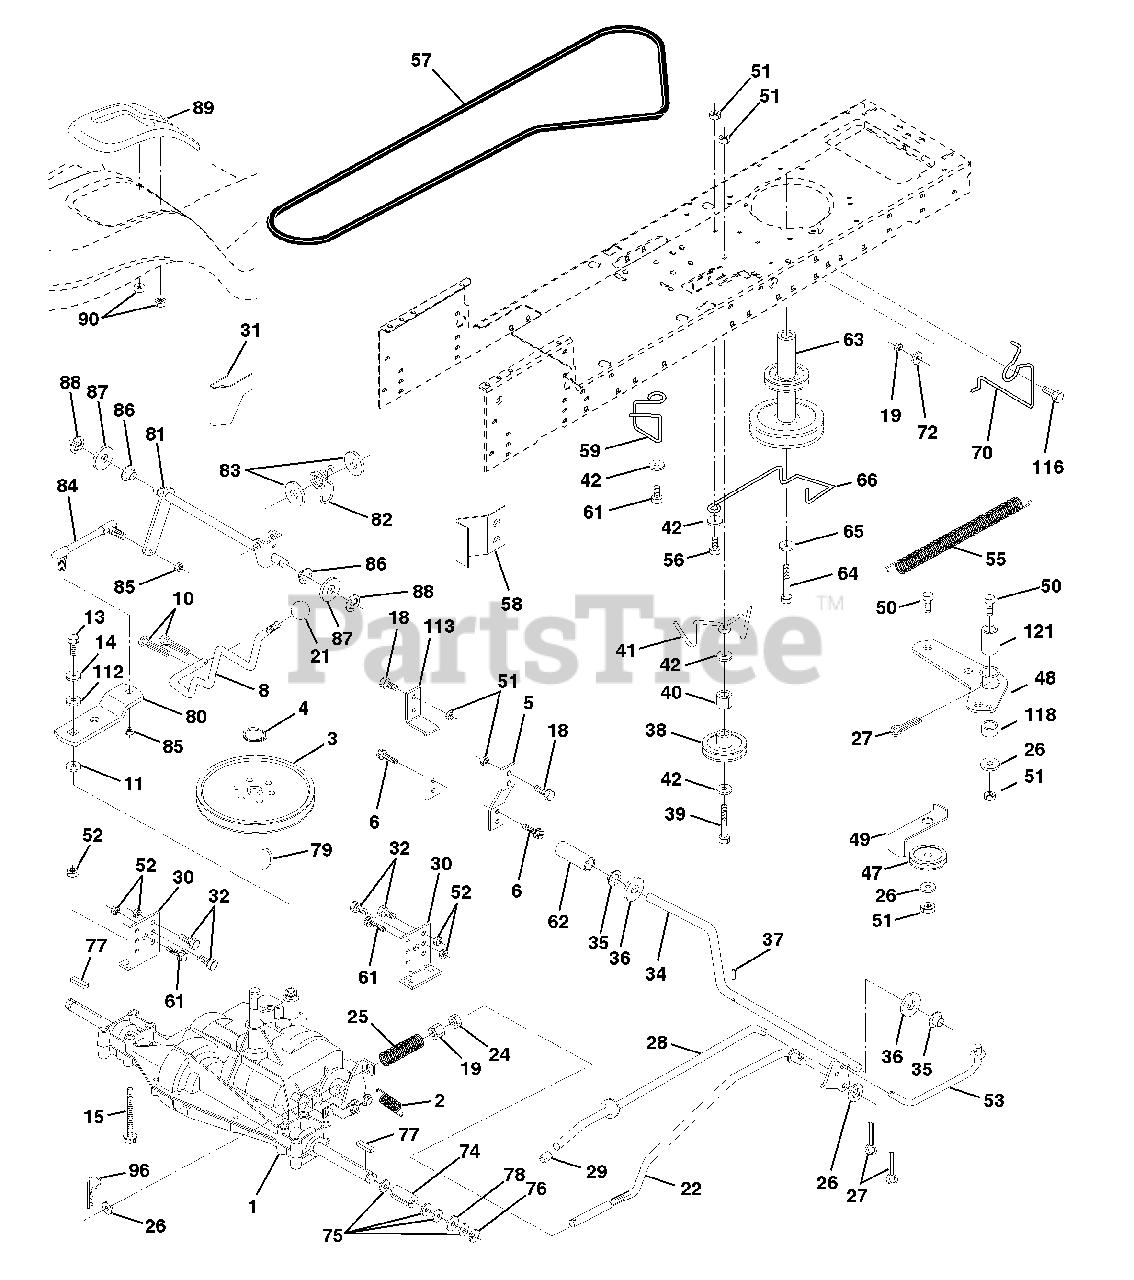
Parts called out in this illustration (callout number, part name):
2	Spring Return Brake T/a Zinc
3	Pulley Transaxle 18" tires
4	Ring Retainer # 5100-62
5	Strap Torque 30 Degrees
6	Screw Thdrol 5/16-18 X 3/4 TYT
8	Rod Shifter
10	Pin Cotter 1/8 X 1 Cad
11	Washer Plate Shf 388 Sq Hole
13	Bolt 1/4-28 Unf Gr 8 W/Patch
14	Washer Lock Hvy Helical 1/4
15	Bolt Hex 5/16-18 Gr. 5
18	Bolt, Fin Hex 3/8-16 UNC x 1 Gr. 5
19	Nut Lock 3/8-16 Unc
22	Rod Brake Blk Zinc 26 840
24	Nut Hex Jam 3/8-16 Unc
25	Spring Rod Brake 2 00 Zinc
26	Washer 13/32 X 13/16 X 16 Ga
27	Pin Cotter 1/8 X 3/4 Cad
28	Rod Brake Parking LT/YT
29	Cap Brake Parking Black
30	Bracket Mtg Transaxle
31	Keeper Belt LH LT 14 Ga
32	Bolt Hex Hd 5/16-18unc X 3/4
34	Shaft Asm Pedal Foot
35	Bearing Nylon Blk 629 Id
36	Washer 21/32 X 1 X 16 Ga
37	Pin Roll 3/16 X 1"
38	Pulley Idler Flat
39	Bolt Fin Hex 3/8-16unc X 2-3/4
40	Spacer Split 395 X 59 Bzp
41	Keeper Belt Retainer Idler Foolproof
42	Washer 13/32 X 13/16 X 12 Ga
47	Pulley Idler V Groove Plastic
48	Bellcrank Asm
49	Retainer Belt Style Spring
50	Bolt Hex Hd 3/8-16unc X 1-1/2
51	Nut Crownlock 3/8-16 Unc
52	Nut Crownlock 5/16-18 Unc
53	Link Clutch
55	Spring Return Clutch 6 75
56	Bolt Fin Hx 3/8-16 X 1/4
57	V-Belt Ground Drive 95 25
58	Keeper Belt RH LT Pnt/zinc 16g
59	Keeper Belt Span Ctr
61	Screw Thdrol 3/8-16x3/4 Ty-tt
62	Cover Pedal Blk Round
63	Engine Pulley LT/YT
64	Bolt Hex
65	Washer Lock Hvy Hlcl Spr 7/16
66	Keeper Belt Engine Foolproof
70	Guide Belt Mower Drive RH
72	Washer 13/32 X 1-1/4 X 12 Ga
74	Spacer Axle
75	Washer 25/32 X 1 1/4 X 16 Ga
76	E-ring #5133-75
77	Key Square 2 0 X 1845/ 1865
78	Washer 25/32 X 1-5/8 X 16 Ga
79	Key Woodruff #9 3/16 x 3/4
81	Shaft Asm Cross 20" t
82	Spring Torsion T/a
83	Washer 17/32 X 3/4 X 16 Ga
84	Rod Shift
85	Nut Lock Center 1/4 - 28 FNTHD
86	Bushing Rod Strg 629/632 Id
87	Washer 21/32 X 1-1/4 X 16 Ga
88	Ring Klip #5304-62
89	Console Shift STLT
90	Nut Self-thd Wsh-hd 1/4 Zinc
96	Retainer Spring 1"
112	Washer 9/32 x 3/4 x 10 Ga.
113	Strap Torque LT
116	Bolt Rdhd Sq Neck 3/8-16 x 1.25
118	Spacer Bellcrank
121	Nyliner Clutching STL
